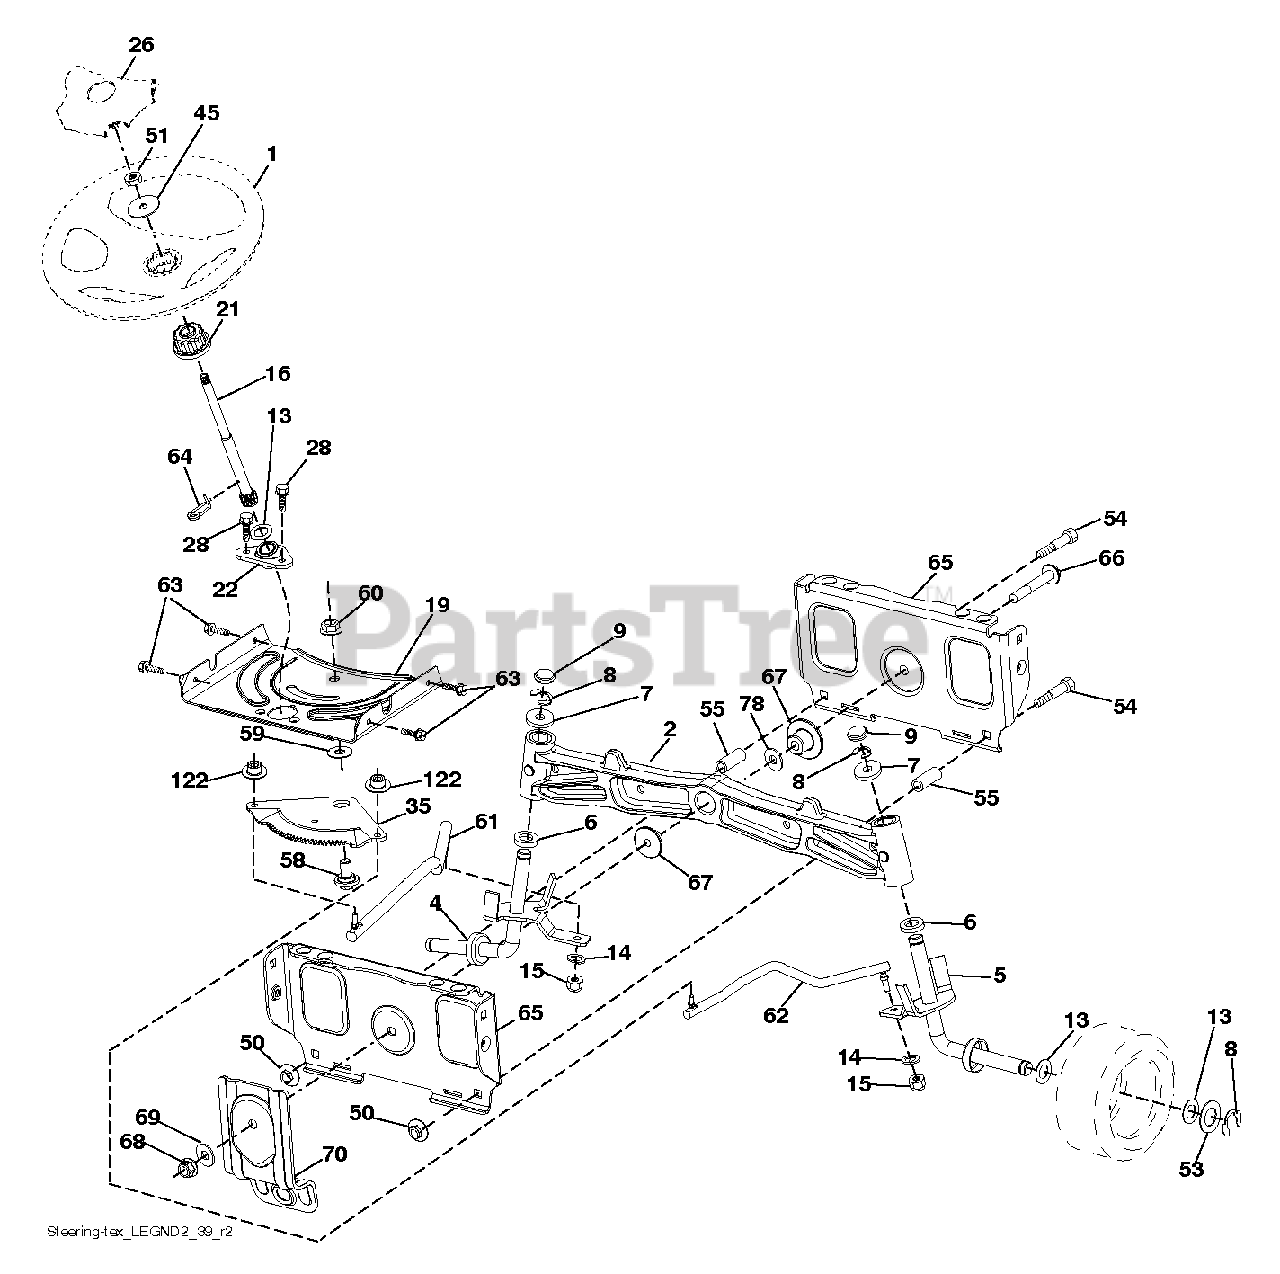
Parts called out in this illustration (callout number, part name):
1	WHEEL.STEER.HUSQ.SR.498.OVMLD
2	AXLE.CAST.IRON
4	SPINDLE.WELDED.LH.16"TEX
5	SPINDLE.WELDED.RH.16"TEX
6	THRUST WASHER
9	CAP.SPINDLE.BLACK
14	WASHER, LOCK 3/8
15	NUT CROWNLOCK 3/8-24
16	SHAFT, STEERING
19	PLATE.STEER.DDL.NLT/NG
21	ADAPTER, WHEEL STNG..
22	STEERING.SUPT.LOWER.
26	INSERT.CAP.WHL.STRG.HUSQ.PREM
28	SCREW, 3/8-16X3/4
35	GEAR.SECTOR.PLATE.DDL.
45	WASHER 9/16"ID, 2 3/8"OD
50	NUT LOCK FLG 3/8-16 UNC
51	NUT.HEX.1/2-20
53	WASHER.HARDENED
55	SPACER.BRACE.AXLE
58	BOLT.SHOULDER.SECTOR.P
59	WASHER.THURST.SECTOR.S
60	NUT FLANGE LOCK 5/8-11
61	DRAGLINK.LH.BALLSTUD.D
62	DRAGLINK.RH.BALLSTUD.D
63	SCREW
64	RETAINER.CLIP.SPRING.S
65	BRACE.AXLE.FRONT.NLT/N
66	BOLT HEX FGHD 7/16-14 X 3 SERR
67	BUSHING.PM.FRONT AXLE
68	NUT.LOCK.FLANGE.7/16
69	WASHER.1.5X.505X.118
70	BRKT.DECK.SUSPENSION.F
78	THRUST WASHER
122	CAP.GEAR.SECTOR.TEX
